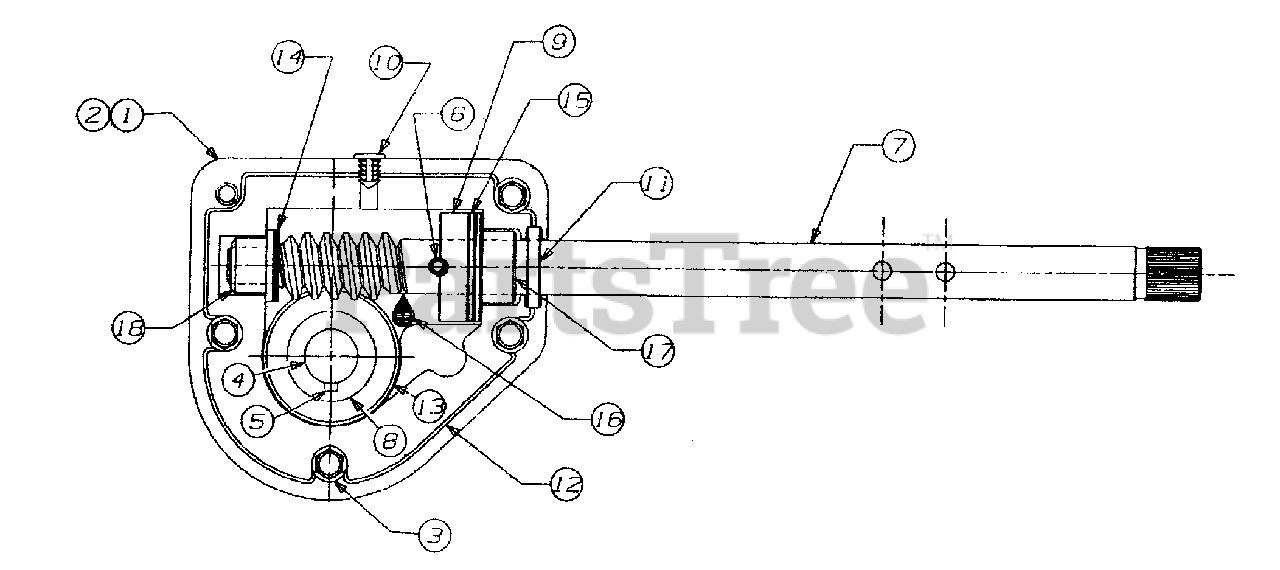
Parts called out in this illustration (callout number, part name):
1	Housing-R.H.
2	Housing-L.H.
4	Axle, Spiral 22" (522E)
5	Key, Hi-Pro, 3/16 x 5/8
6	Pin, Spiral, .25 x 1.25
7	Worm, Shaft
8	Gear, Worm, 20T
9	Collar, Thrust
11	Seal, Oil, .75 x 1.131 x .188
12	Sealant, Loctite Ultra Grey 5699
13	Washer, Flat, .76 x 1.5 x .03
14	Washer,Flat, .5 x 1.0 x .02
15	Washer, Flat, .76 x 1.5 x .06
16	Grease
17	Bearing, Flange, .75 ID x 1.0 OD
18	Bearing, Flange, .75 x 1.0 x .925
